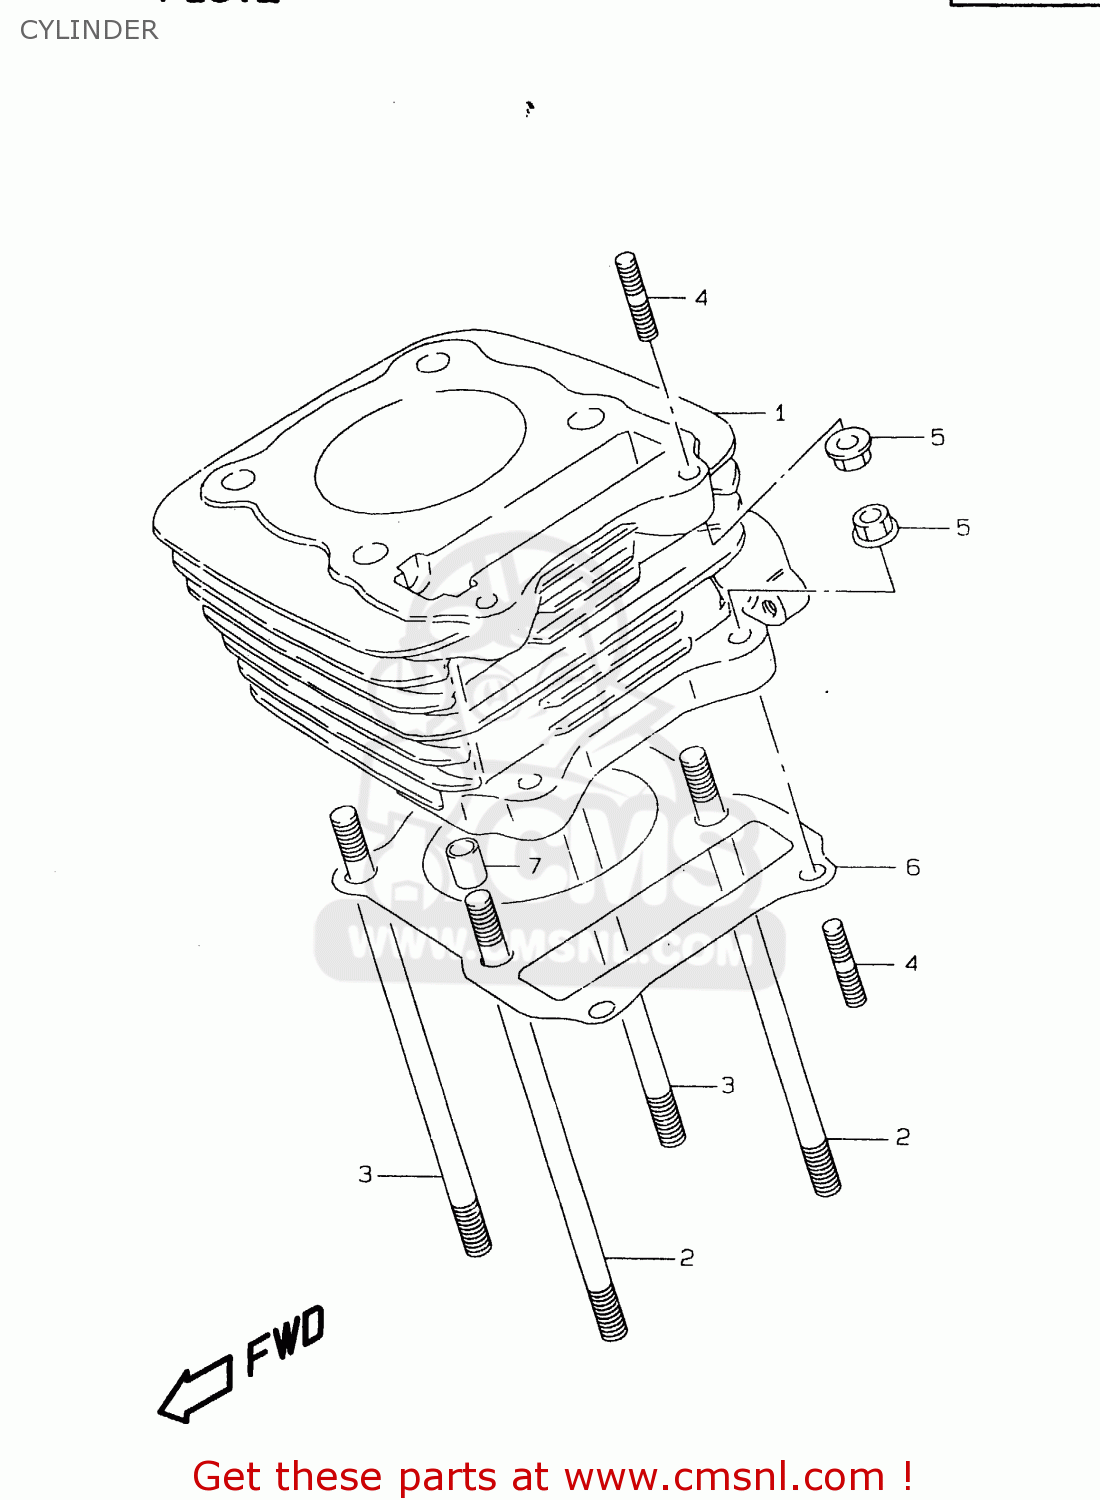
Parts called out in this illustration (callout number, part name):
1	CYLINDER COMP
2	BOLT,STUD
3	BOLT,STUD
4	STUD BOLT
5	NUT
6	GASKET,CYLINDER (NAS)
7	PIN
